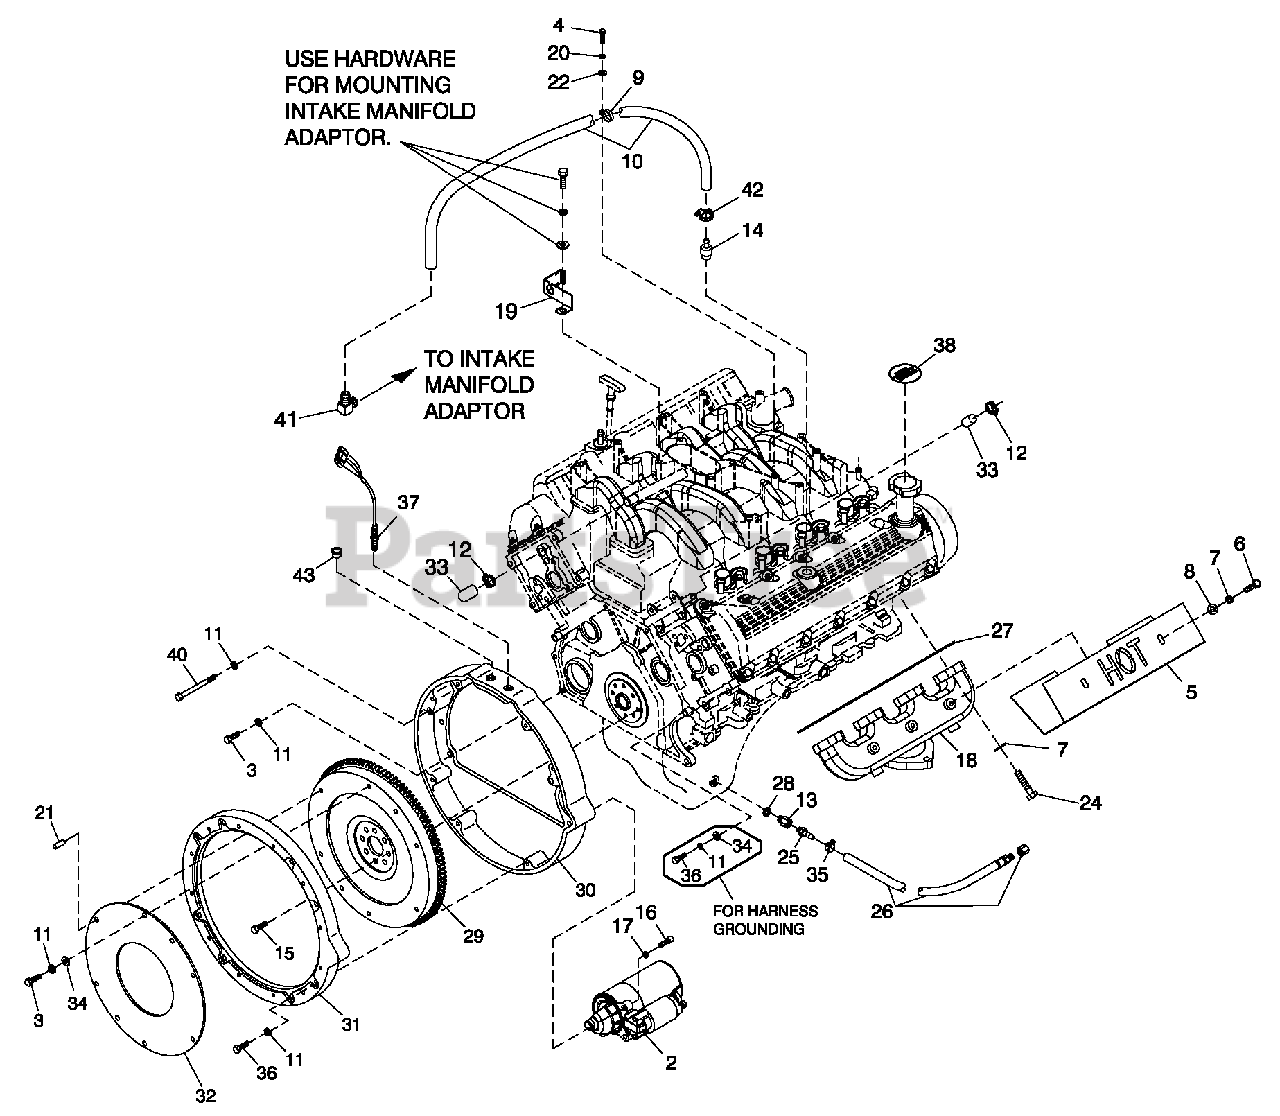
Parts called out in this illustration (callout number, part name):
2	STARTER MOTOR 12V
3	SCREW SHC M10-1.5 X 35 G12.9
4	SCREW HHC M6-1.0X 16 G8.8
5	HEAT SHLD EXHAUST MANIFOLD
6	SCREW HHC 5/16-18 X 1/2 SSTL
7	WASHER LOCK M8 SSTL
8	WASHER FLAT M8 SS
9	CLAMP VINYL .75 X .343Z
10	HOSE 3/8 ID SINGLE BRAID (15" LG)
11	WASHER LOCK M10
12	CLAMP HOSE #10 .56-1.06
13	ADAPTER M14-1.50X 3/8 NPT
14	VALVE, PCV (FORD 6.8L)
15	SCREW HHC M10-1.0 X 25 G10.9
16	SCREW SHC M8-1.25 X 30 G12.9
17	WASHER LOCK M8-5/16
18	MACHINED MANIFOLD EXHAUST 5.4L
19	BRACKET SIGNAL CONDITIONER
20	WASHER LOCK M6-1/4
21	DOWEL PIN M10 X 24
22	WASHER FLAT 1/4 ZINC
24	SCREW SHC M8-1.25X35 SS
25	BARBED STR 3/8 NPT X 3/8
26	HOSE DRAIN ASSY 28"
27	GASKET EXHAUST MANIFOLD
28	WASHER NYLON .565
29	ASSEMBLY 6.8L G-BOX FLYWHEEL
30	FLYWHEEL HOUSING MACH 6.8L V10
31	COVER FLYWHEEL MACH 6.8L V-10
32	PLATE DAMPNER RETNR
33	CAP HOSE
34	WASHER FLAT 3/8-M10 ZINC
35	HOSE CLAMP BAND 5/8"
36	SCREW SHC M10-1.5 X 25 G12.9
37	ASSY MAGPICKUP(3/8-24 MALE)
38	DECAL REFER TO OWNERS MANUAL
40	SCREW SHC M10-1.50 X 100 G10.9
41	BARBED EL 90 1/4 NPT X 3/8
42	CLAMP HOSE #5.5.62-.62
43	PLUG PLASTIC 3/8 NPT
